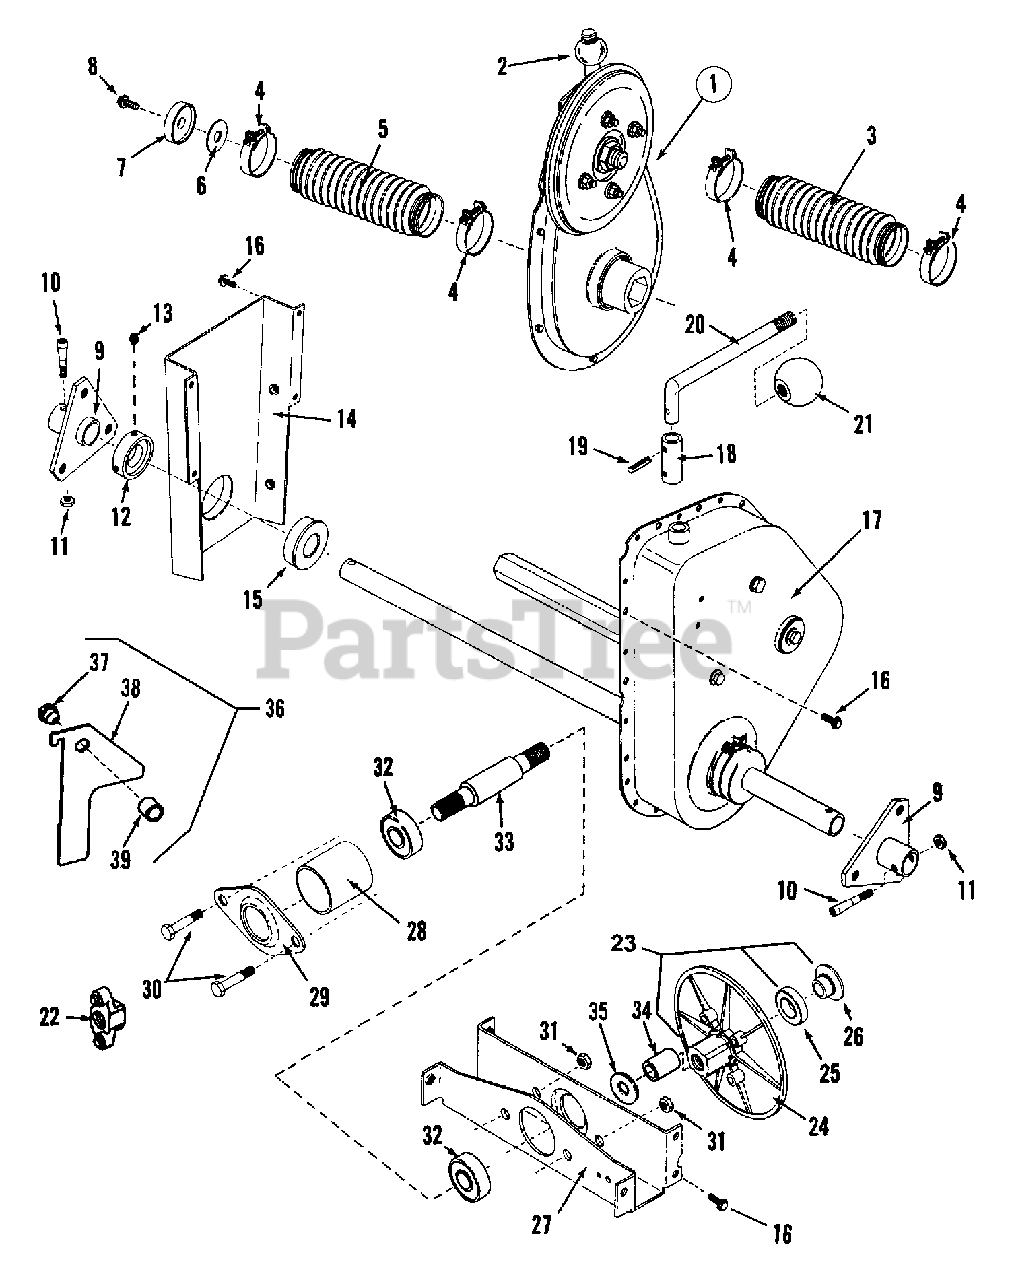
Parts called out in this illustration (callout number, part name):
1	PRIMARY CHAIN CASE
2	BUSHING, Primary Clutch
3	BOOT, Left Side Oil seal
4	CLAMP, Boot
5	BOOT, Oil Seal
6	WASHER, Thrust
7	SPACER, Hex Tube
8	SCREW, 3/8-16 x 1" Hex Washer Self-Tap
9	HUB, Rear Wheel
10	BOLT, Tapered
11	NUT, 5/16-24 Hex Lock
12	LOCK-COLLAR
13	SETSCREW 5/16-18 x 5/16"
14	ASSEMBLY, Axle Support
15	BEARING, Ball
16	SCREW,5/16-18 x 5/8" Hex Washer Self-Tap
17	ASSEMBLY, Transmission
18	COUPLING, Shift Lever
19	ROLL-PIN, 3/16 x 3/4"
20	LEVER, HI-LO Shifter
21	KNOB, Shifter Ball
22	HUB, Flex Coupling
23	ASSEMBLY, Drive Disc
24	DISC, Drive
25	BEARING, Ball
26	BUTTON, Center
27	SUPPORT, Bearing
28	TUBE
29	RETAINER
30	SCREW, 5/16-18 x 3" Hex Head
31	NUT, 5/16-18 Hex Center Lock Grade B or 5
32	BEARING, Ball
33	SPINDLE, Drive Disc 5.040" Long
33	SPINDLE, Drive Disc (1985 model) 6.040" Long
34	SPACER, Drive Disc, 1"
35	WASHER, Shim
36	KIT, Drive Disc Gauge
37	PLUG, Plastic 5/8-18
38	GAUGE PLATE, Disc Adjustment
39	EXTENSION, Shaft
